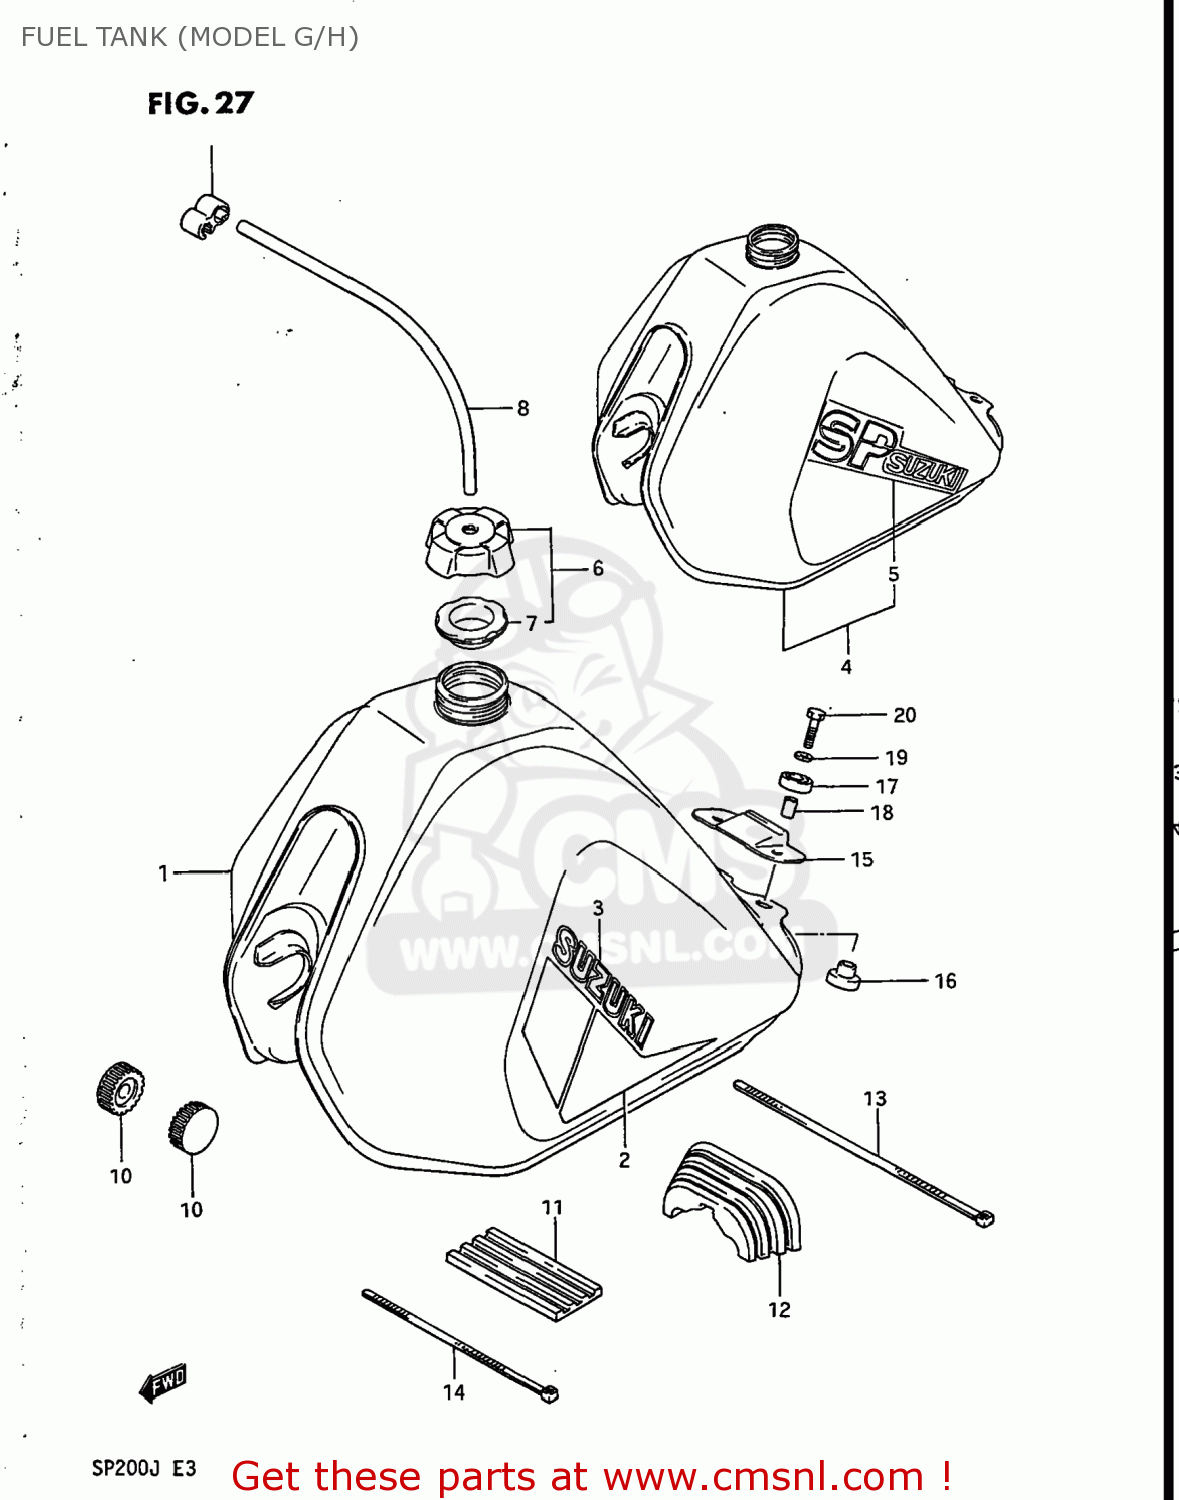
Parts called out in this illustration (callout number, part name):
1	TANK ASSEMBLY,FUEL
2	TAPE SET,FUEL TANK
3	EMBLEM(WHITE)
4	TANK ASSEMBLY,FUEL
5	TAPE SET,FUEL TANK
6	CAP SET,FUEL TANK
7	GASKET (NAS)
8	HOSE
9	CLAMP,FUEL TANK BREATHER HOSE
10	CUSHION
11	CUSHION,FUEL TANK UPR FR
12	CUSHION,FUEL TANK RR
13	CLAMP(L:250)
14	CLAMP
15	PLATE,SEAT FR HOOK
16	CUSHION
17	CUSHION
18	SPACER
19	WASHER,LOCK
20	BOLT
